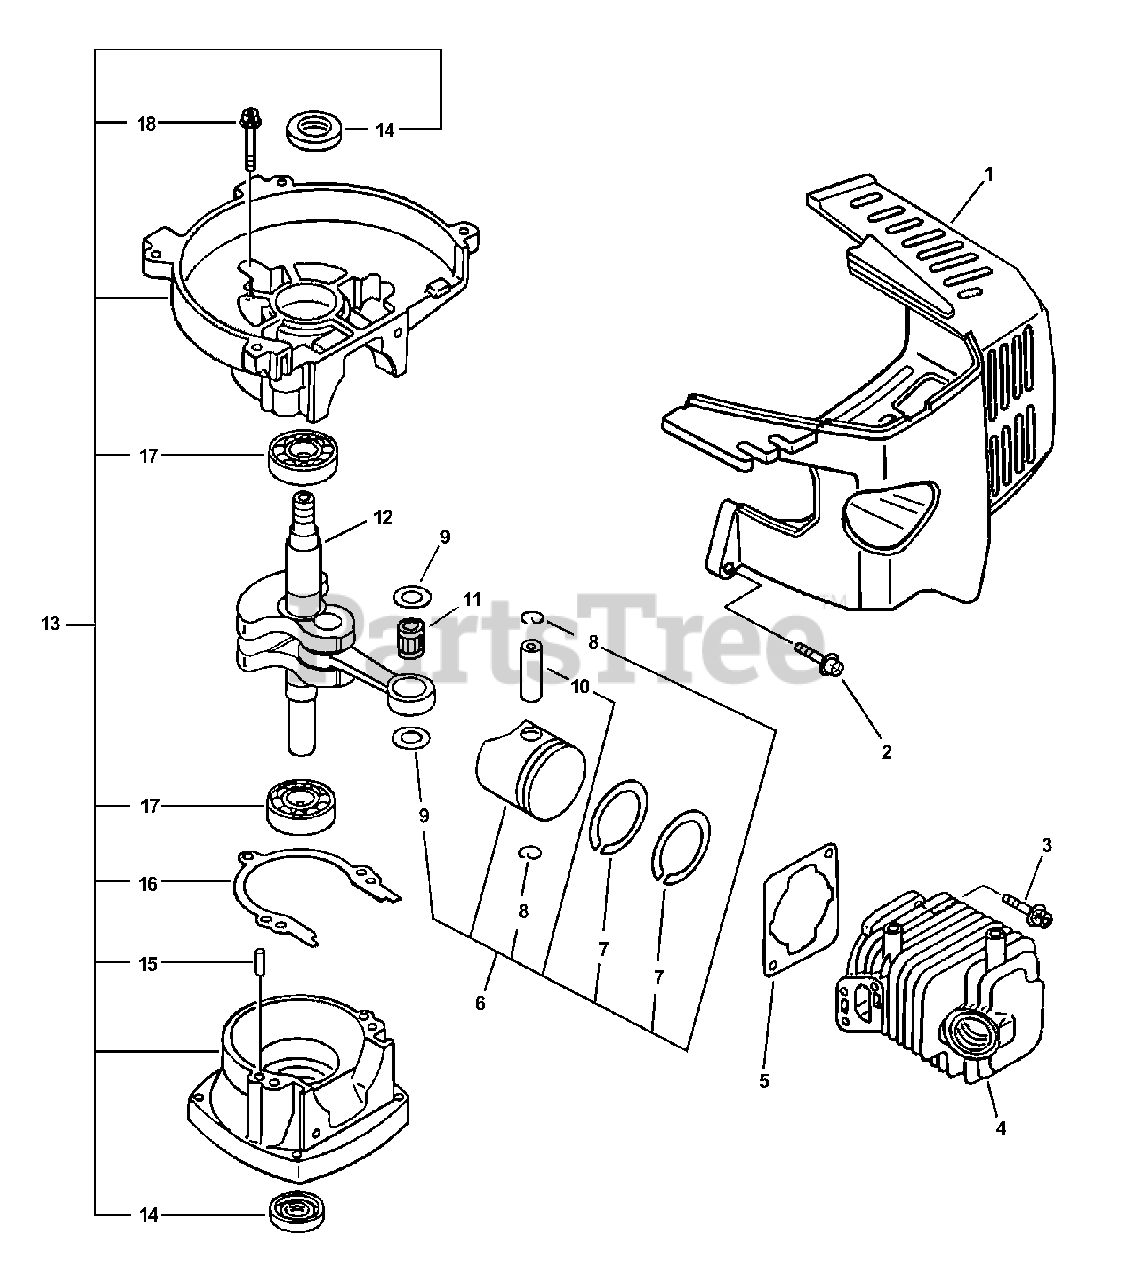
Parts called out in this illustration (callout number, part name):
1	COVER, ENGINE
2	SCREW - 4X22
3	SCREW - 5X22
4	CYLINDER
5	GASKET, CYLINDER
6	PISTON KIT
7	RING, PISTON
8	RING, RETAINING
10	PIN, PISTON
11	BEARING, NEEDLE - 8
12	CRANKSHAFT ASSY
13	CRANKCASE KIT
14	SEAL, OIL
15	PIN - LOCATING
16	GASKET, CRANKCASE
17	BEARING, BALL - 6201
18	SCREW - 5X28
